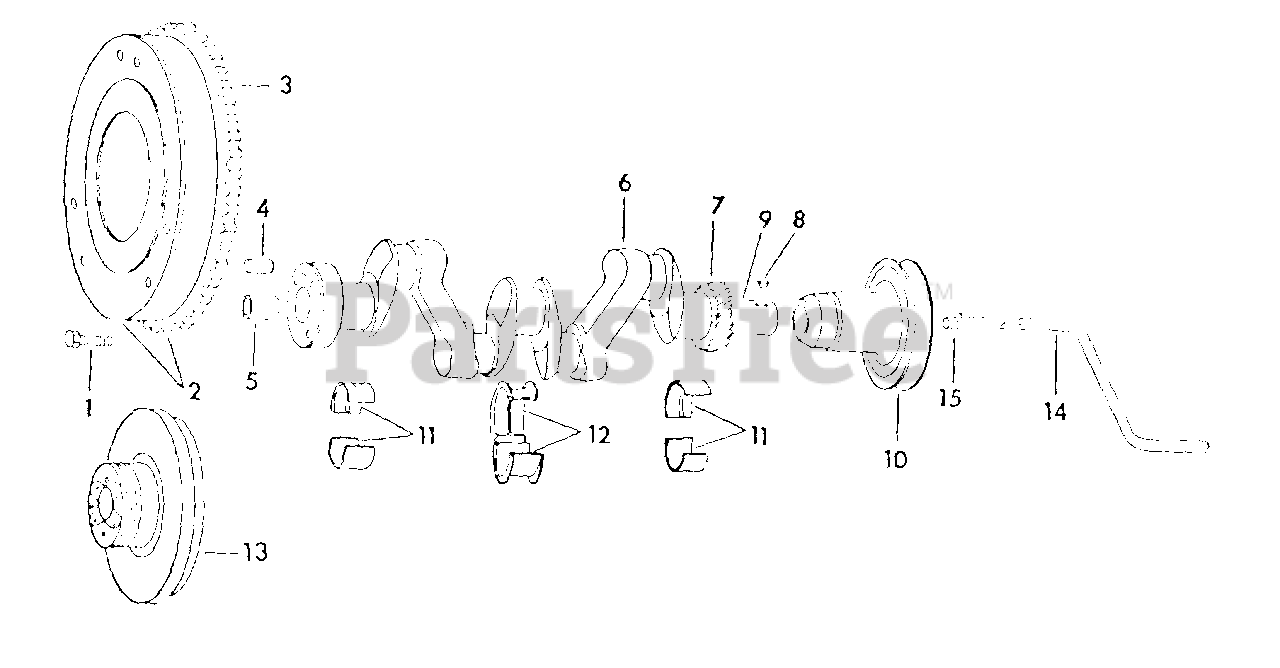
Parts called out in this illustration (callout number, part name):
1	BOLT, 3/8-24 X 1-1/4 TYPE 4 FLYWHEEL
2	FLYWHEEL W/RING GEAR
3	GEAR, FLYWHEEL RING - 84 T
4	PIN, FLYWHEEL DOWEL
5	BUSHING, CLUTCH PILOT
6	CRANKSHAFT W/BEARINGS -STD-
7	PINION, CRANKSHAFT - 18 T
8	KEY, 5/32 X 5/8 WOODRUFF 6 ALY-STL -CRANKSHAFT PINION-
9	KEY, 5/32 X 5/8 WOODRUFF 6 ALY-STL -FAN DRIVE PULLEY-
10	PULLEY, FAN DRIVE
11	BEARING ASSY, CRANKSHAFT FRONT AND REAR STD
11	BEARING ASSY, CRANKSHAFT FRONT AND REAR .002 U/S-
12	BEARING ASSY, CRANKSHAFT CENTER .010 U/S
13	NOT USED IN THIS APPLICATION
14	CRANK, STARTING, W/PIN IH-351011-R1
15	PIN, STARTING CRANK
